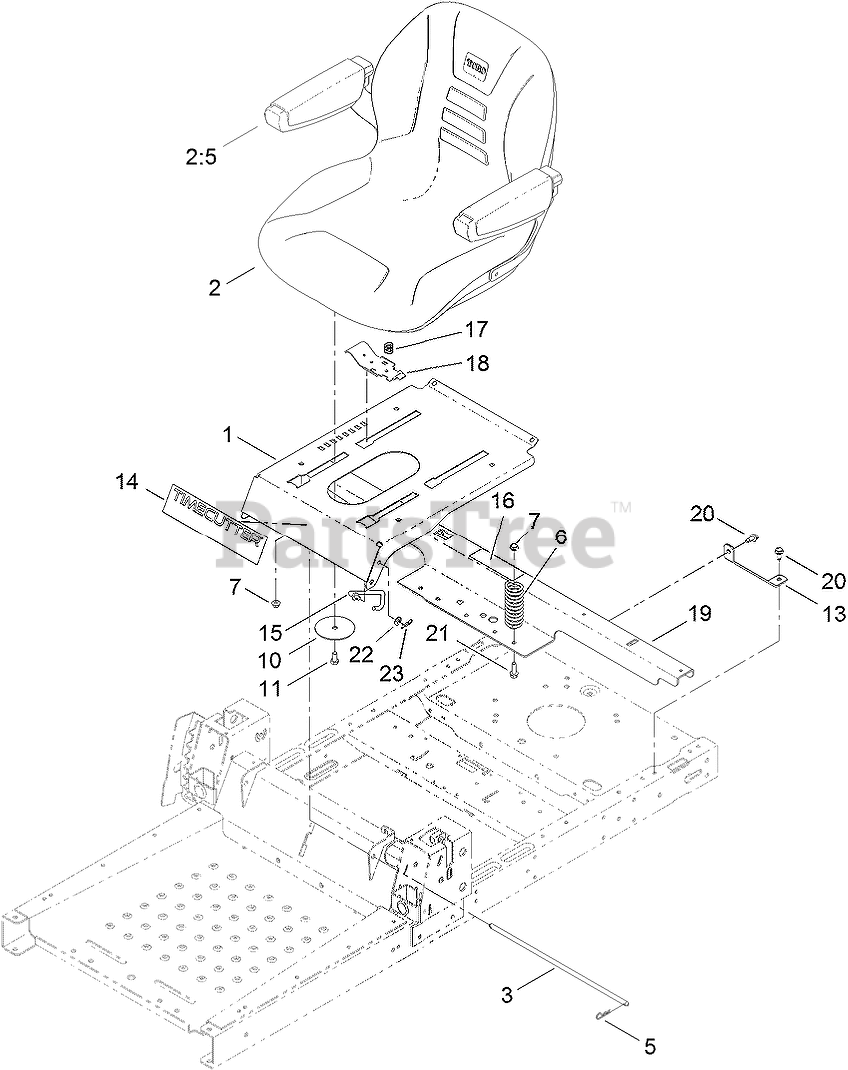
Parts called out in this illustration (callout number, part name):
1	PAN-SEAT
2	18 INCH SEAT ASM
2:5	ARMREST KIT
3	ROD-STOP
5	PIN-COTTER
6	SPRING-COMPRESSION
7	NUT-HF, NI
10	WASHER-SEAT
11	SCREW-HH
13	SUPPORT-TANK, REAR
14	DECAL-TIMECUTTER
15	STOP-SEAT
16	DECAL-SERVICE, CE
17	SPRING-COMPRESSION
18	LATCH-SEAT
19	SUPPORT-POD
20	SCREW-HWHTF
21	SCREW-HHF
22	WASHER-PLAIN
23	PIN-COTTER
